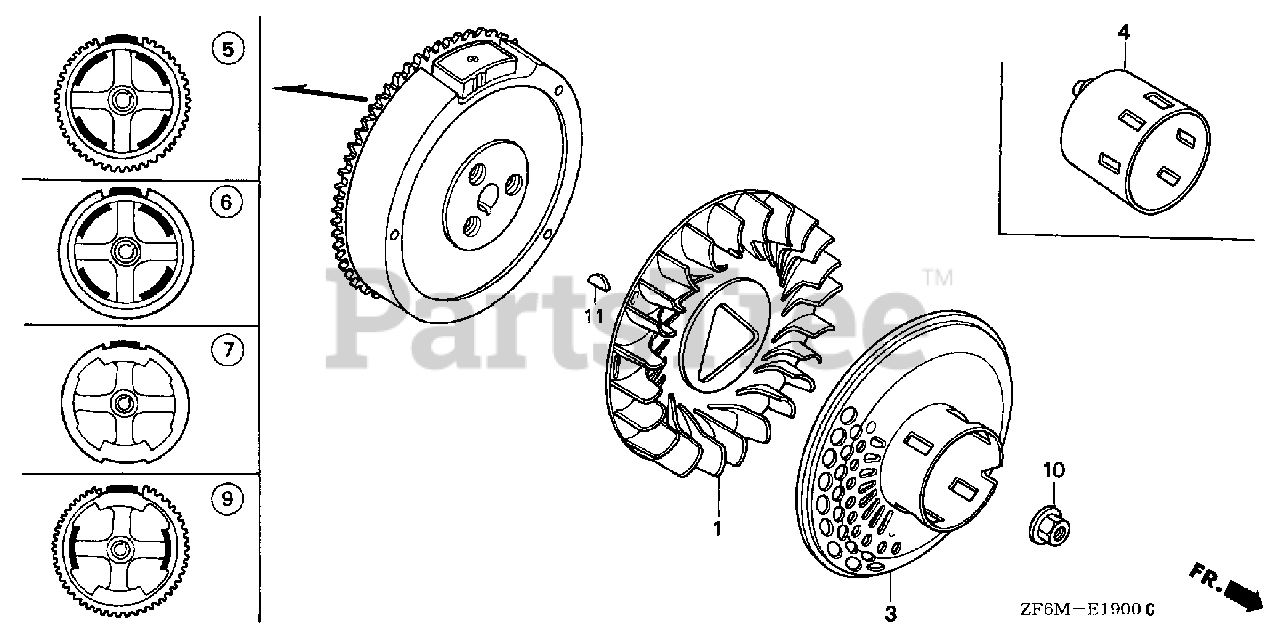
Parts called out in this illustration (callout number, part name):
1	FAN, COOLING
3	PULLEY, STARTER (SCREEN GRID)
7	FLYWHEEL
10	NUT, SPECIAL (16MM) (1)
11	KEY, SPECIAL WOODRUFF (25X18)
